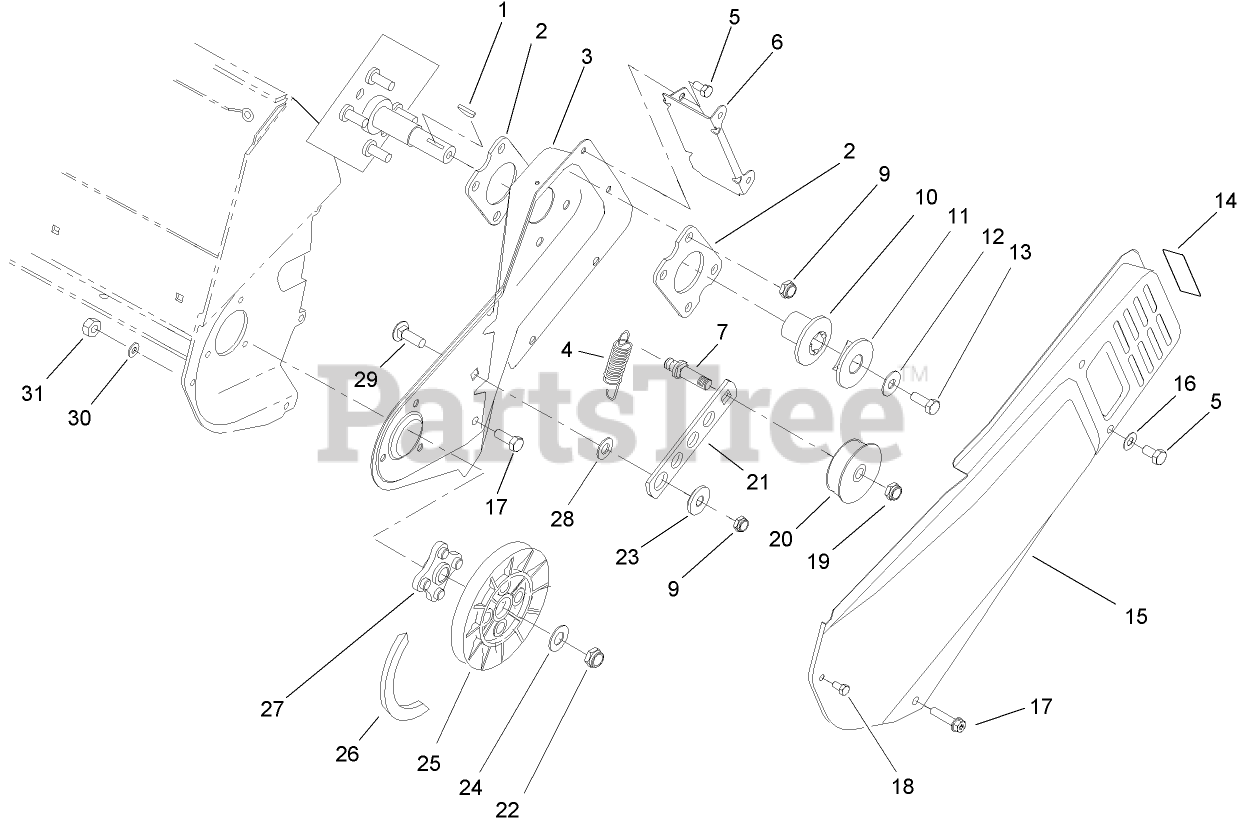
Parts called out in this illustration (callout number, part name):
1	KEY-WOODRUFF
2	PLATE-ENGINE
3	SIDEPLATE-LH
4	SPRING-EXTENSION
5	SCREW-HWH
6	BRACKET-COVER, BELT
7	PIN-IDLER
9	NUT-LOCK, NI
10	HUB-HALF SHEAVE
11	CAP-HALF SHEAVE
12	WASHER-FLAT
13	SCREW-HH
14	DECAL-WARNING
15	COVER-BELT
16	WASHER-FLAT
17	SCREW-PLASTIC
20	PULLEY-IDLER
21	ARM-IDLER
22	NUT-LOCK, NI
23	BUSHING-IDLER
24	WASHER-FLAT
25	PULLEY-DRIVEN
26	V-BELT
28	WASHER
29	SCREW-CARR
30	WASHER-FLAT
31	NUT-LOCK, NI
